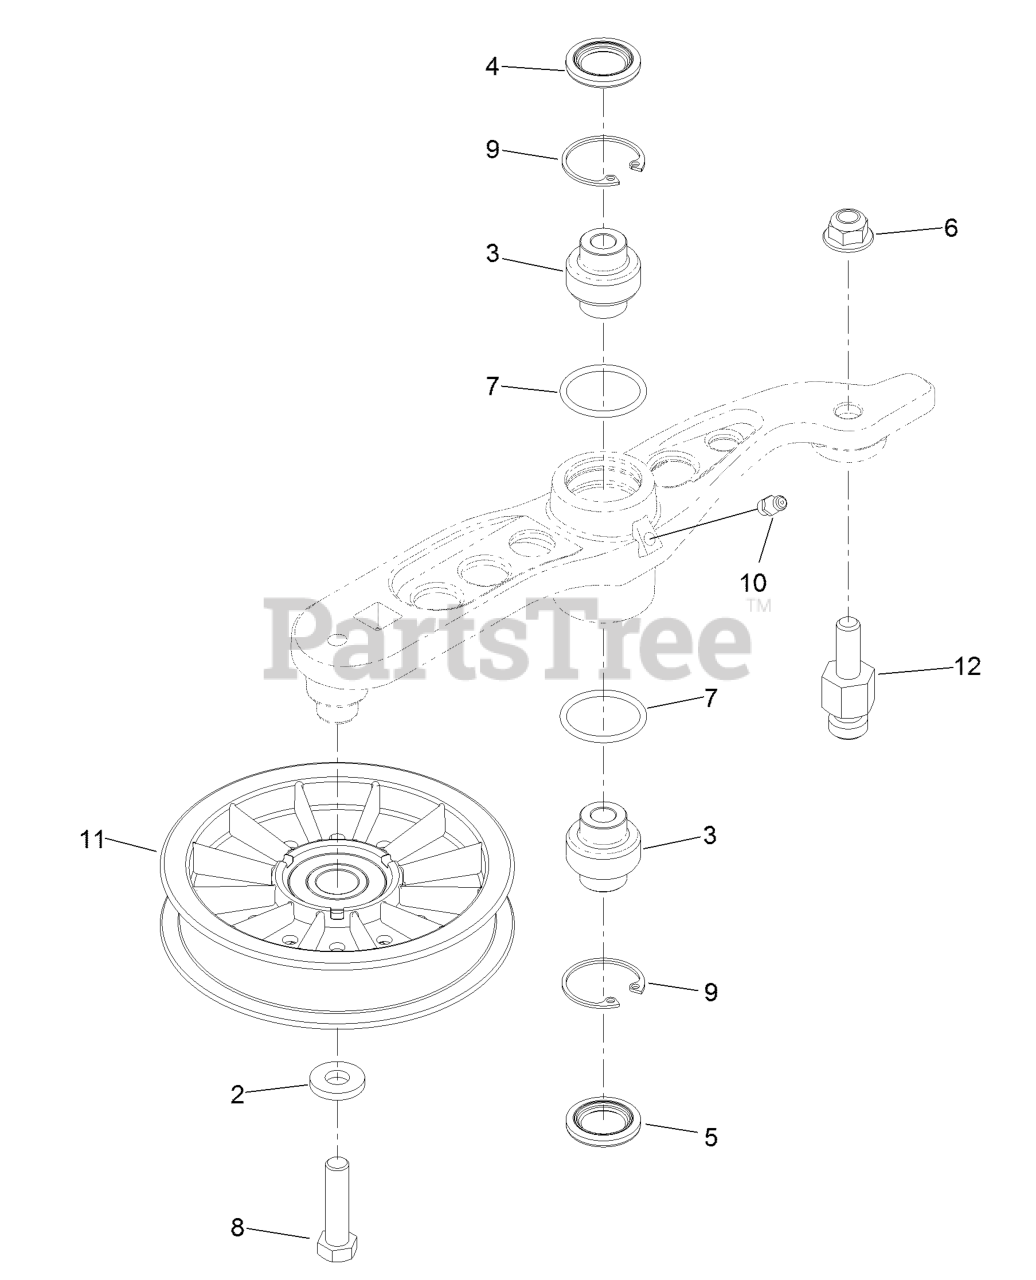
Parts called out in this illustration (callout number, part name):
3	BEARING-SPHERICAL
4	SEAL-LIP, DOUBLE
5	SEAL-LIP, SINGLE
6	Nut-Nyloc 3/8-16 Flg
8	SCREW-HH
9	RING-SNAP
10	FITTING-GREASE
11	PULLEY-IDLER
